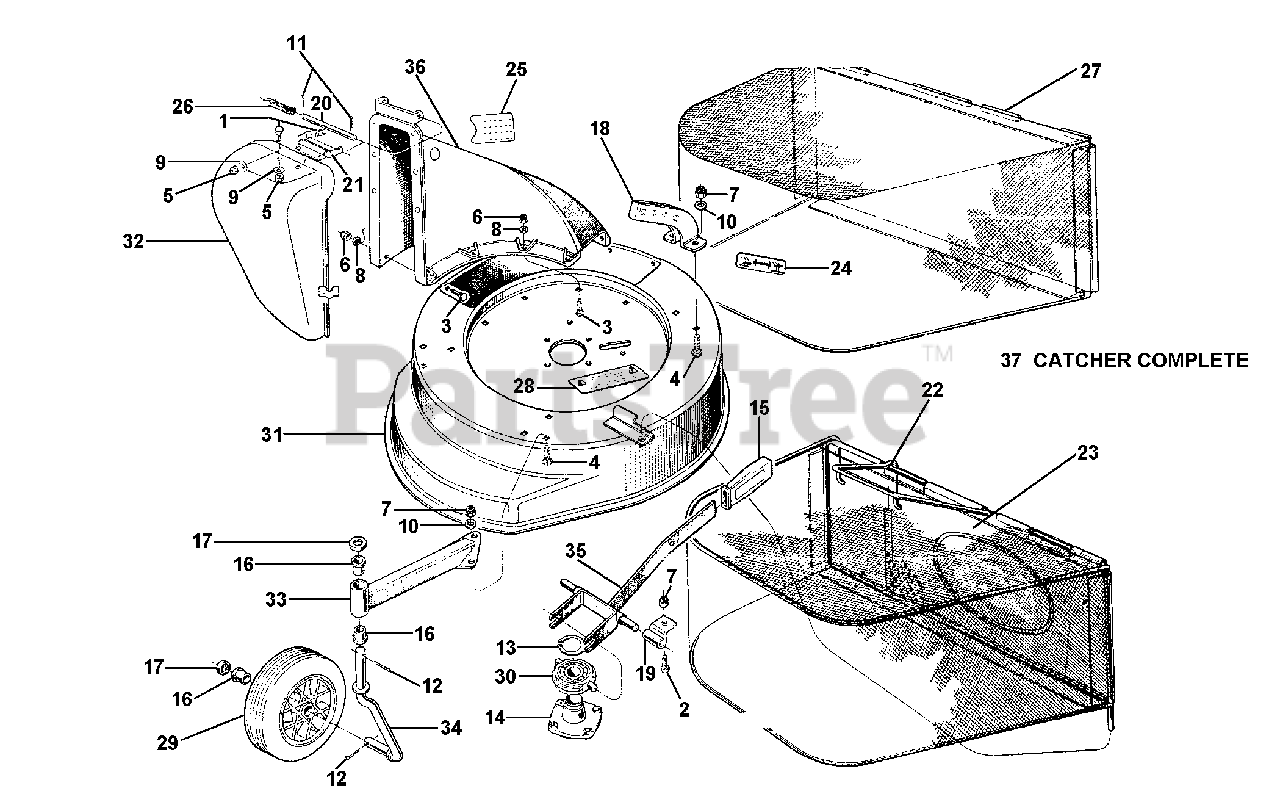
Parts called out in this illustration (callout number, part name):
1	SCREW M5X10
2	SCREW M8X16
3	SCREW M6X20
4	SCREW TTQ M8X20 UNI 5731
6	NUT, SELF LOCKING M6
7	NUT, SELF LOCKING M8
8	WASHER, FLAT 6,4
9	SUPER WASHER
10	WASHER, LOCK 8,4
12	PIN, COTTER 4X25
13	EXT. CIRCLIP D 35
14	BLADE HOLDER HUB
18	CUTTING HEIGHT SELECTOR
24	TRANSFER FOR LAWNMOWER
26	DEFLECTOR SPRING
29	SMALL WHEEL
31	LAWN MOWER CRANKCASE
33	WHEEL SUPPORT
35	ADJUSTING LEVER
37	CATCHER COMPLETE
